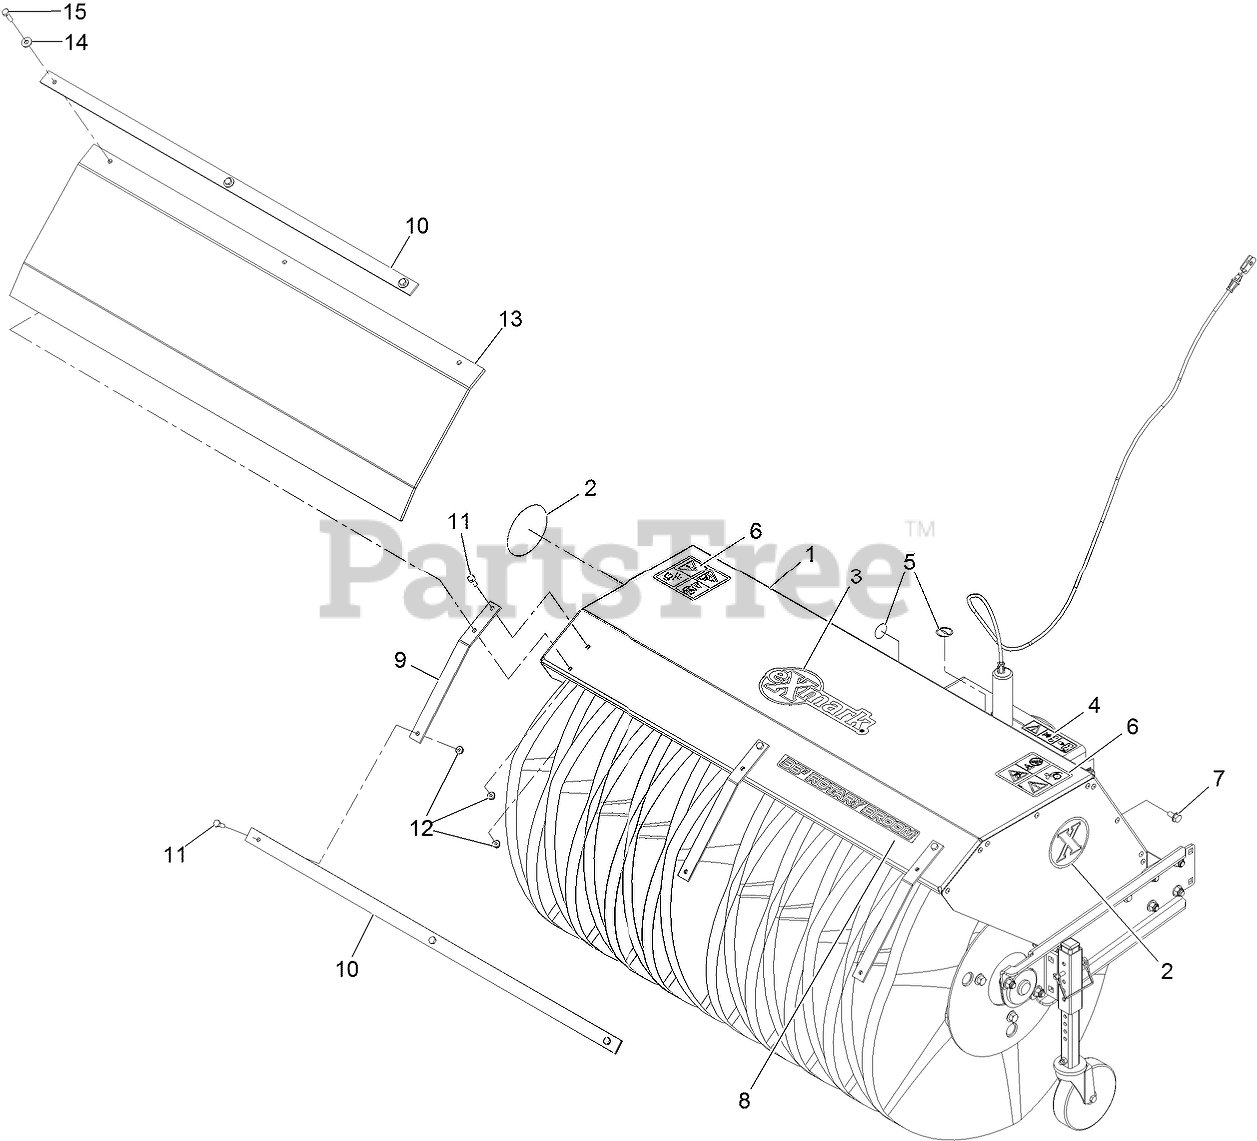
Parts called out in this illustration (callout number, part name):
1	Broom ASM
2	DECAL-EXMARK X-LOGO 3.85
3	DECAL, EXMARK LOGO
4	DECAL-COVER, MISSING
5	DECAL-GREASE
6	DECAL-WARNING
7	SCREW-HWHTF
8	DECAL-36 ROTARY BROOM
9	STRAP-SUPPORT, DEFLECTOR
10	STRAP-SUPPORT, BROOM DEFL
11	SCREW-HH
13	DEFLECTOR-BROOM
14	WASHER-FLAT
15	SCREW-HH
